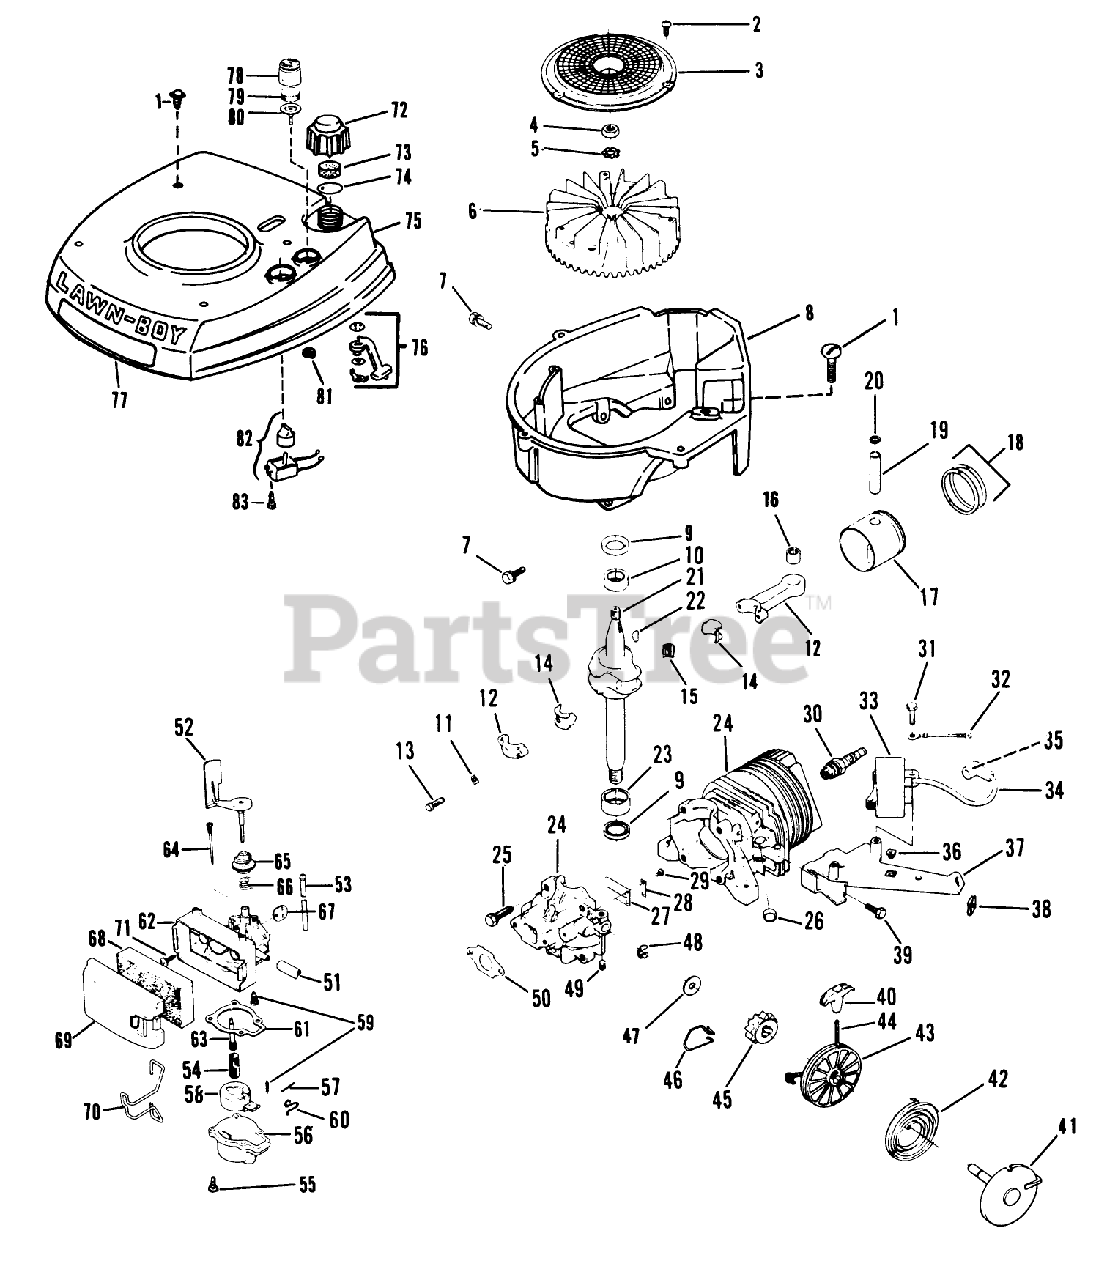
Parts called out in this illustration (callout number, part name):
1	SCREW S
2	SCREW F
7	SCREW-SEMS
8	SHRD BASE & EYELET
10	BEARING V
13	SCREW
14	LINER ASM
16	BEARING AY F
20	RING-RETAINING
22	KEY
23	BEARING V
25	SCREW S
26	PLUG-CORE VF
28	PLATE-BACKUP, REED
34	HT LEAD&COVER XEV
36	NUT-CLIP
38	NUT - SPEED S
42	SPRING S
43	Pulley
46	SPRING F
47	WASHER S
50	GASKET CARB S
51	GAS LINE
52	AIR VANE&SHAFT S
53	TUBING PRIMER S
54	FILTER-FUEL VS
55	SCREW-HH
62	CARB BODY S
64	NEEDLE ADJ. AY S
65	COLLAR-ADJUST, AIRVANE
66	SPRING-THRO. S
67	DISC S
70	RETAINER-COVER, FILTER
71	SCREW
73	BAFFLE - FOAM SM
74	GASKET S
79	FILTER S
81	LOCKNUT S
